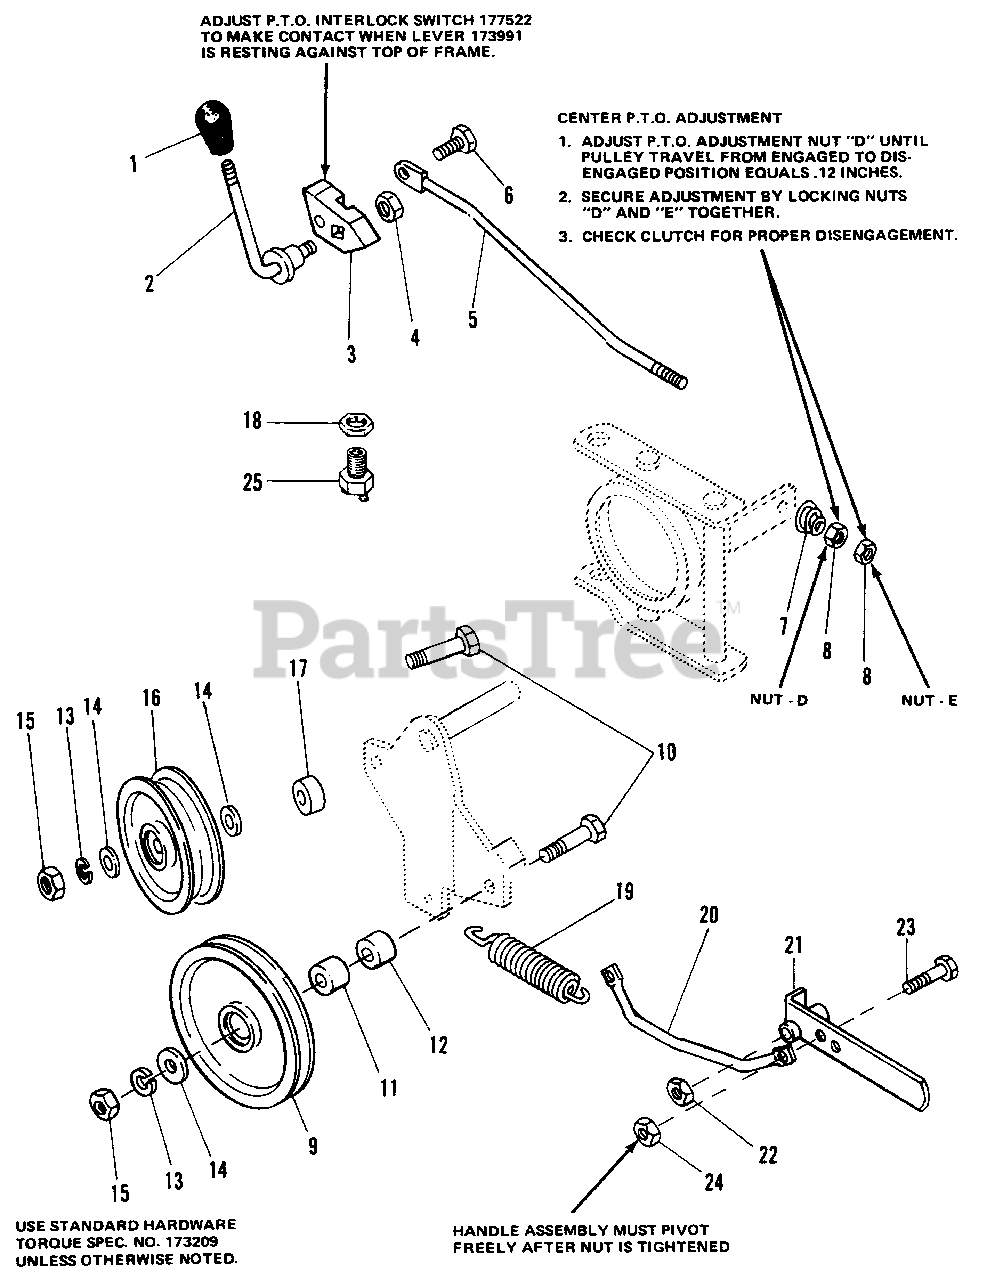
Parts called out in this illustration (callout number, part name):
1	KNOB
2	HANDLE, Clutch P.T.O.
4	LOCKNUT. Hex, 3/8-16
5	CONTROL ROD ASSEMBLY
6	CAPSCREW, Special
8	NUT, Hex, Full, 5/16-18
10	CAPSCREW, Hex Hd., 3/8-16 x 2
13	LOCKWASHER, 3/8
14	WASHER, 5/16
15	NUT, Hex, Full, 3/8-16
18	NUT, Pal
19	SPRING, Tension
20	ROD, Tension
21	HANDLE ASSEMBLY
22	LOCKNUT, Hex, 7/16-14
23	CAPSCREW, Hex Hd., 5/16-18 x 3/4
24	LOCKNUT, Hex, 5/16-18
25	SWITCH, Interlock
